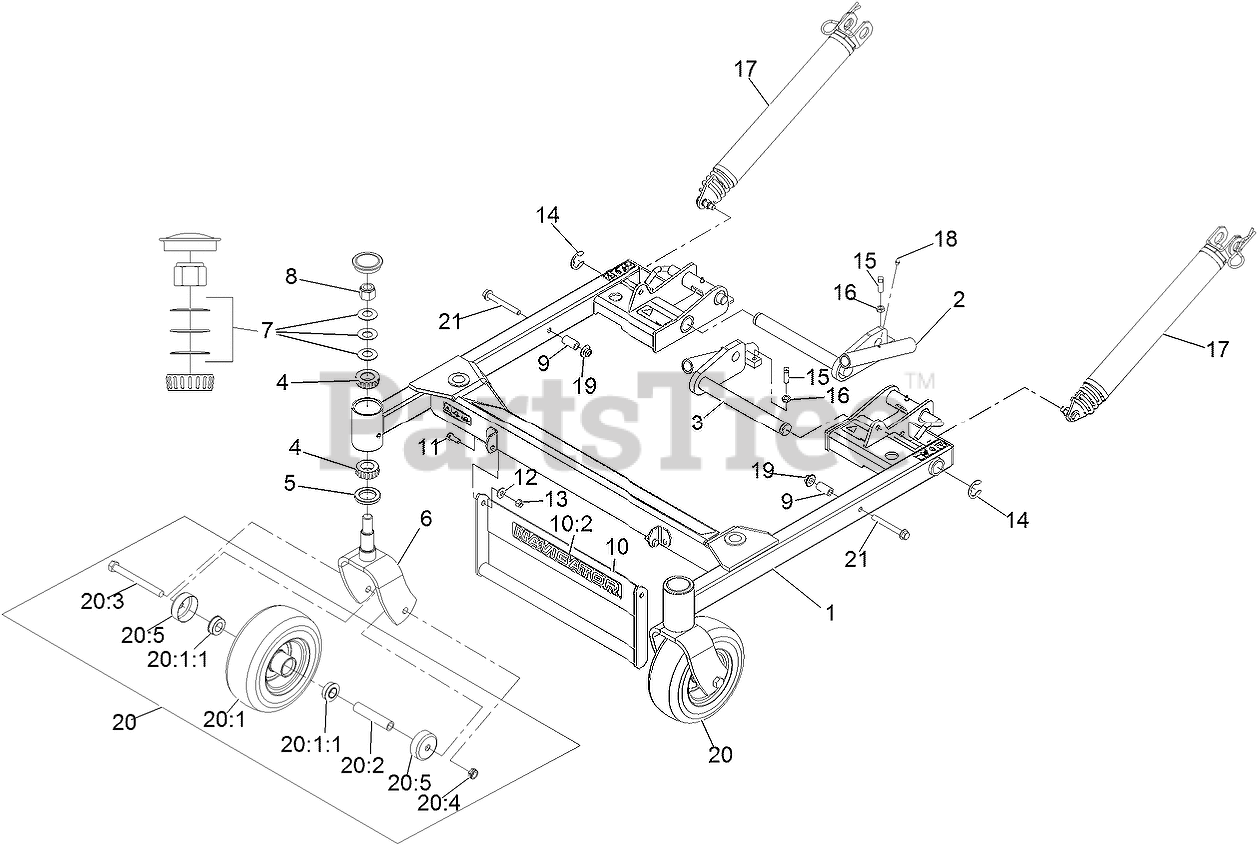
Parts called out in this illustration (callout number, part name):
1	Frame-Deck Support W/Decals
2	PIVOT-DECK, RH
3	PIVOT-DECK, LH
4	Cone-Bearing Tapered Roller
5	SEAL-GREASE
6	FORK-CASTER
7	WASHER-BELLVILLE
8	NUT-LOCK, NI
10	ASM,DECK LIFT HANDLE W/DECAL
10:2	DECAL-NAVIGATOR LOGO
11	SCREW-HH
12	WASHER-SPRING
13	NUT-LOCK, NI
14	RING-SNAP
15	SCREW-SET, SQH
16	NUT-JAM
17	LIFT ASSIST SPRING ASM
18	FITTING-GREASE
19	Nut-Nyloc 3/8-16 Flg
20	ASM,FF CASTER WHEEL W/AXLE
20:1	ASM,WHEEL AND TIRE
20:1:1	Bearing-Ball
20:2	SPACER-CASTER, FRONT
20:3	SCREW-HH
20:4	NUT-HEX
20:5	GUARD-SEAL
21	Screw-HHF
